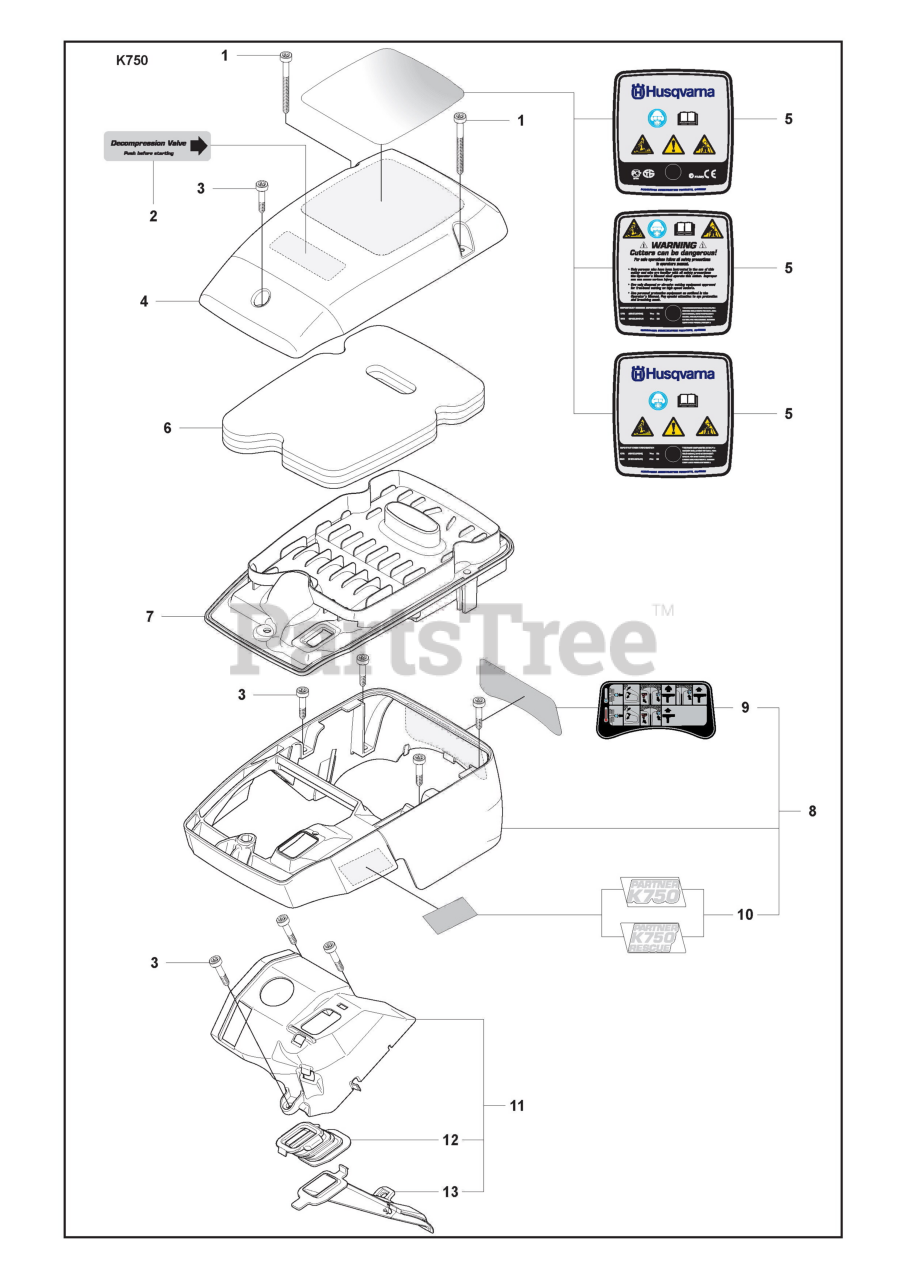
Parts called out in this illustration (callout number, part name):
4	FILTER COVER
5	LABEL
7	FILTER BOTTOM
8	CYLINDER COVER ASSY
10	LABEL
11	COVER
12	BELLOWS
13	AIR NOZZLE
